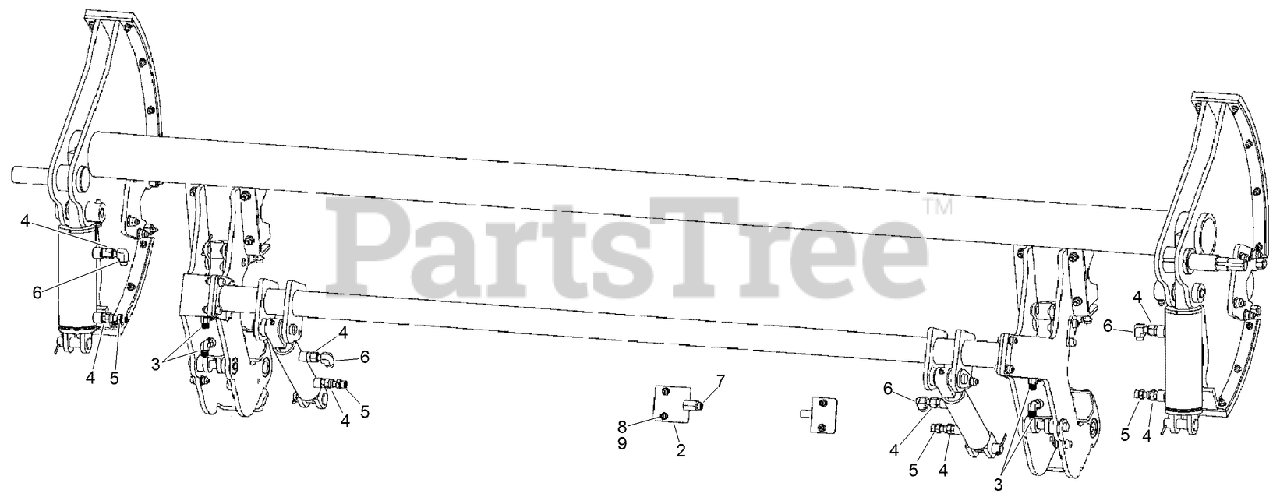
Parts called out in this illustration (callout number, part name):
2	PLATE - Mount
3	CONNECTION - 90 Deg, -4 ORFS / -4 ORB
4	CONNECTION - Straight, -4 ORFS / -6 ORB
5	FITTING-STRAIGHT
6	CONNECTION - 90 Deg, -4 ORFS / -4 ORFS
7	FITTING-TEE
8	SCREW-HHF
9	NUT, METRIC FLANGE PREVAILING - M6 Zinc
